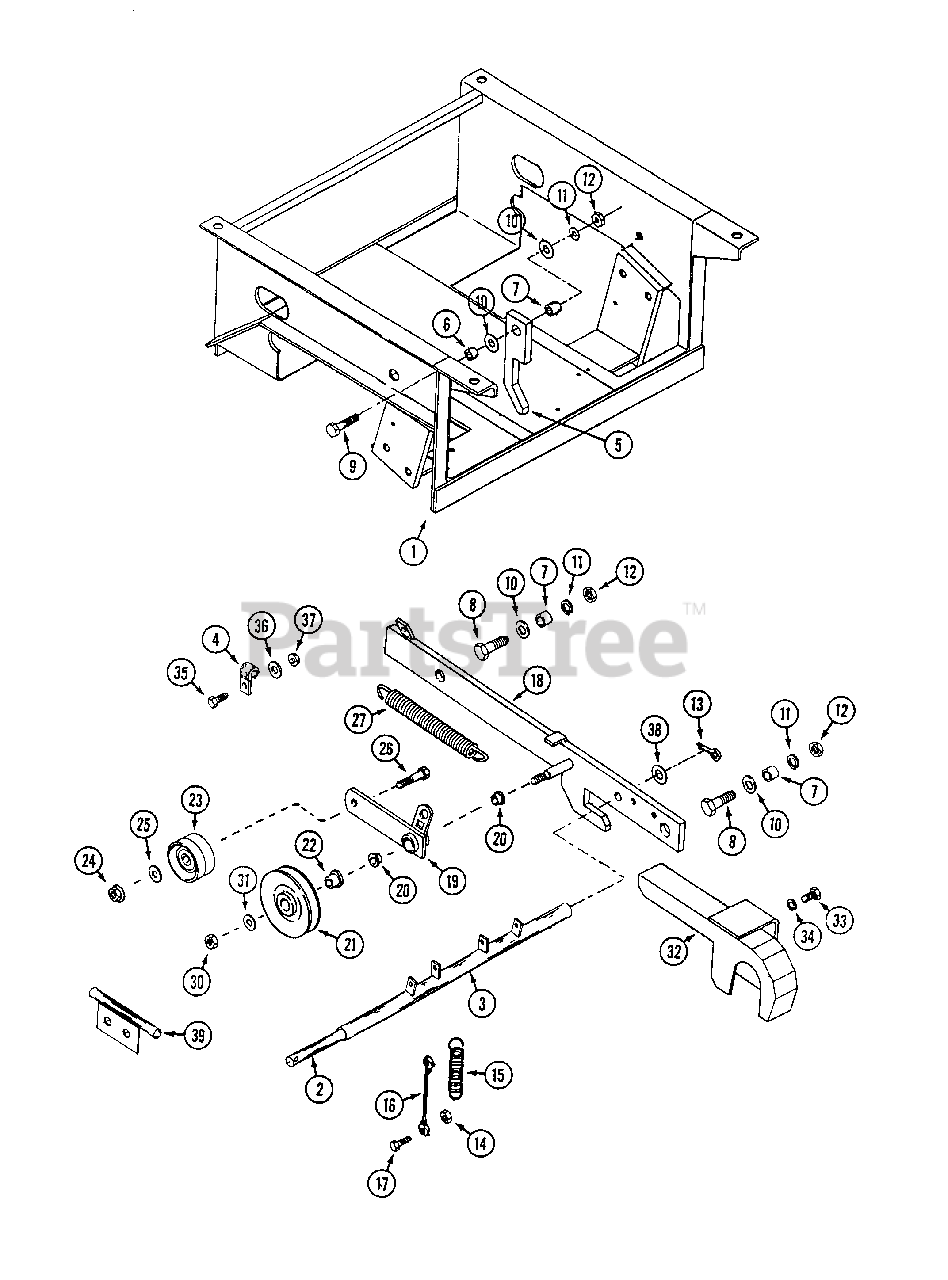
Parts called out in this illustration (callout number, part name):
1	BASE
2	PIN - cross bar
4	CLIP - "J"
5	LOCK - forward nose down
6	BUSHING - pivot (3/8" long)
7	BUSHING - pivot (1/2" long)
8	BOLT - 1/2" - 13 x 1-1/2"
9	BOLT - 1/2" - 13 x 2-1/4"
10	WASHER - 1/2"
11	LOCKWASHER - 1/2"
12	NUT - 1/2" - 13
13	PIN - cotter 1/8" x 1"
14	NUT - lock 1/4" - 20
15	SPRING - lift assist
17	BOLT - 1/4" - 20 x 1"
18	ARM - deck L.H.
18	ARM - deck R.H.
18	ARM - deck R.H..
19	ARM - idler
20	BEARING - flange
21	PULLEY - "V" idler
22	BUSHING - pulley
23	PULLEY - idler, flat
24	NUT - 3/8" - 16 flange lock
25	WASHER - 3/8"
26	BOLT - 3/8" - 16 x 2"
27	SPRING - extension
30	NUT - 1/2" - 13 lock
32	GUARD - belt
33	BOLT - 5/16" - 18 x 3/4"
35	BOLT - 5/16" - 18 x 1"
36	WASHER - 5/16"
37	NUT - 5/16" - 18 flange lock
38	WASHER - 9/16"
39	TUBE - wire
